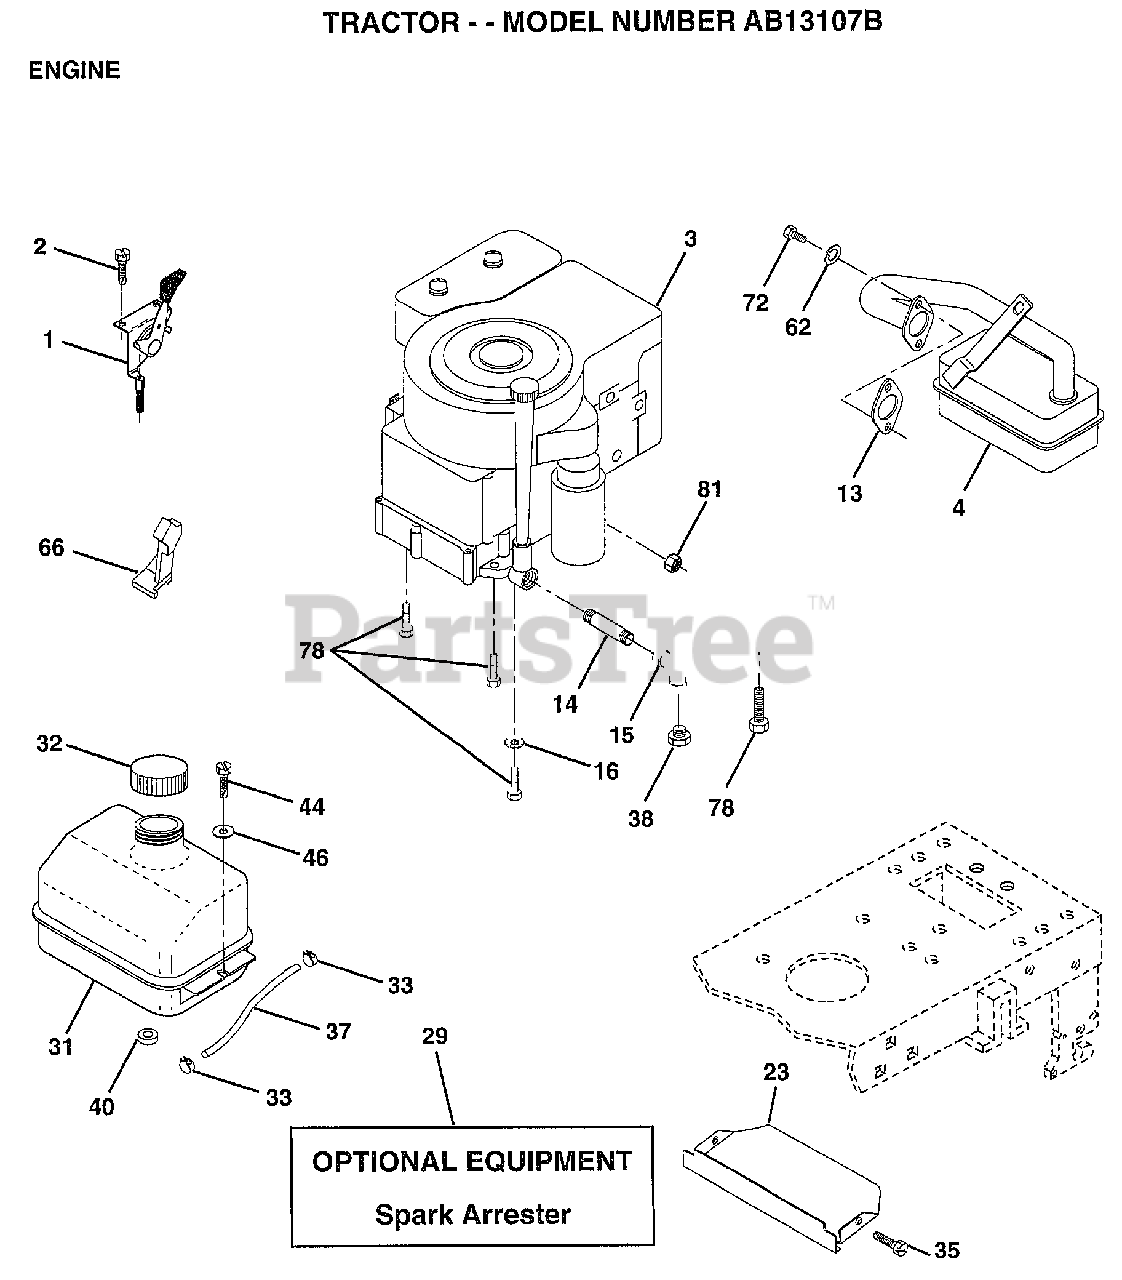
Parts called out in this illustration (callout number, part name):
1	CONTROL.THTL.23.5
2	SCREW LT
4	MUFFLER
14	PIPE NIPPLE
15	ELBOW
16	LOCKWASHER
23	SHIELD.BRN/DBR.GD
31	TANK.FUEL.LT.
32	CAP ASM FUEL
33	HOSE CLAMP
35	SCREW
37	LINE FUEL
44	SCREW HEX CRT
46	WASHER
62	LOCKWASHER
66	"STOP,DASH THROTT"
72	SCREW
78	SCREW
81	NUT
